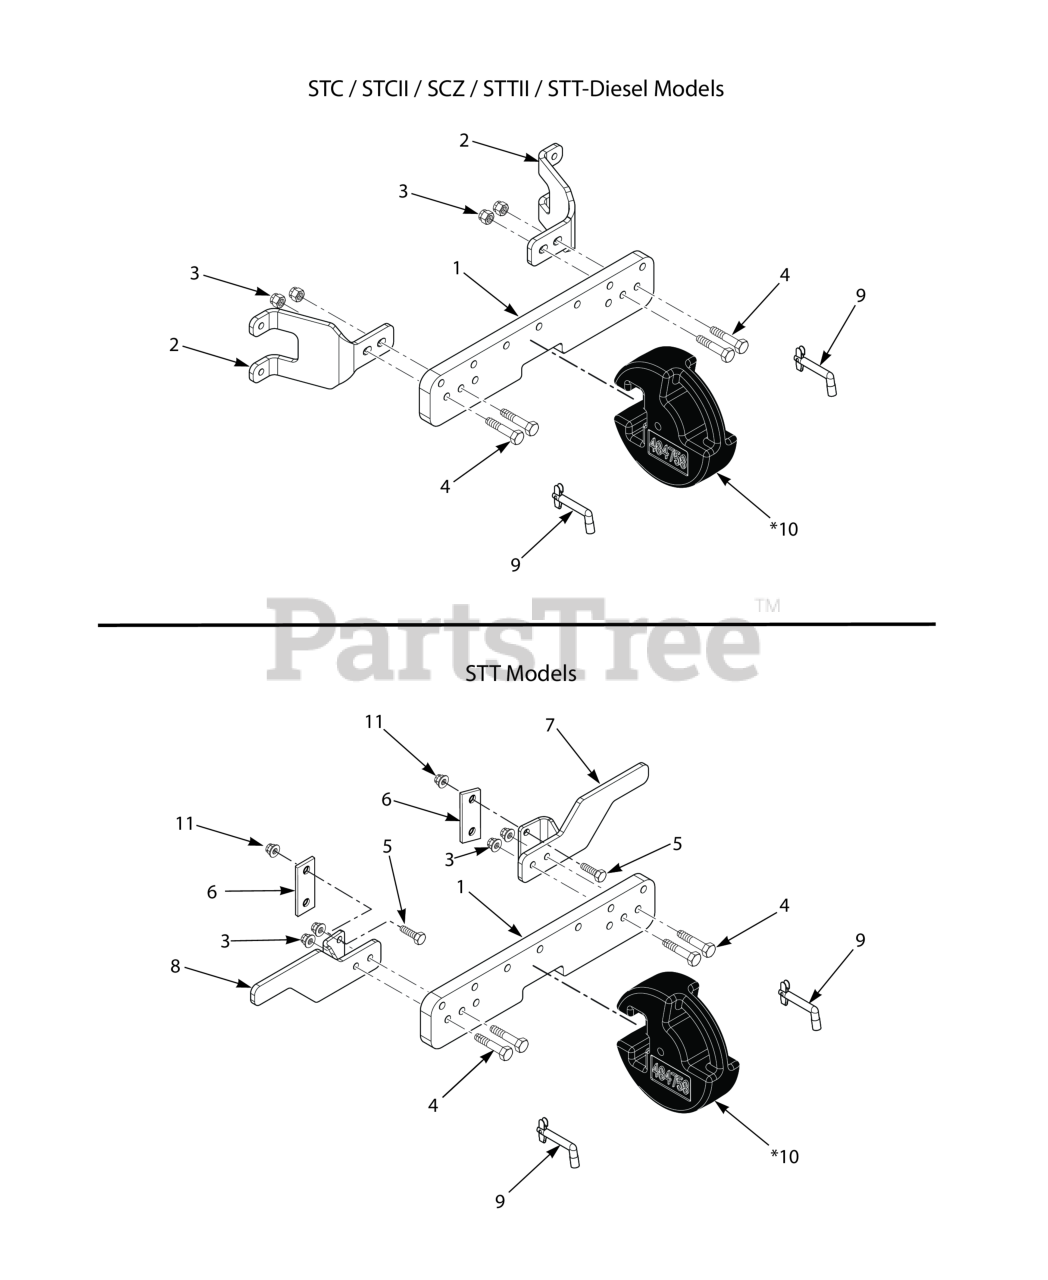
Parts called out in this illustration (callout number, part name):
1	Weight Bar
2	Bracket, LH Weight Bar (STC / STCII & SCZ48/52)
3	Nut, Elastic Stop 1/2-13, (STT-52 & STTII-52)
4	HEX HD. BOLT 1/2-20 X 2 SPECIAL
5	Bolt, Hex Head 3/8-16 x 1-1/2" B&S 32BV
6	Clamp, Bar
7	Mounting Bracket Weldment, LH Weight Bar
8	Mounting Bracket Weldment, RH Weight Bar
9	Pin, Weight Retention
10	Weight
11	Nut, Flange Elastic Stop Nut, 3/8-16
